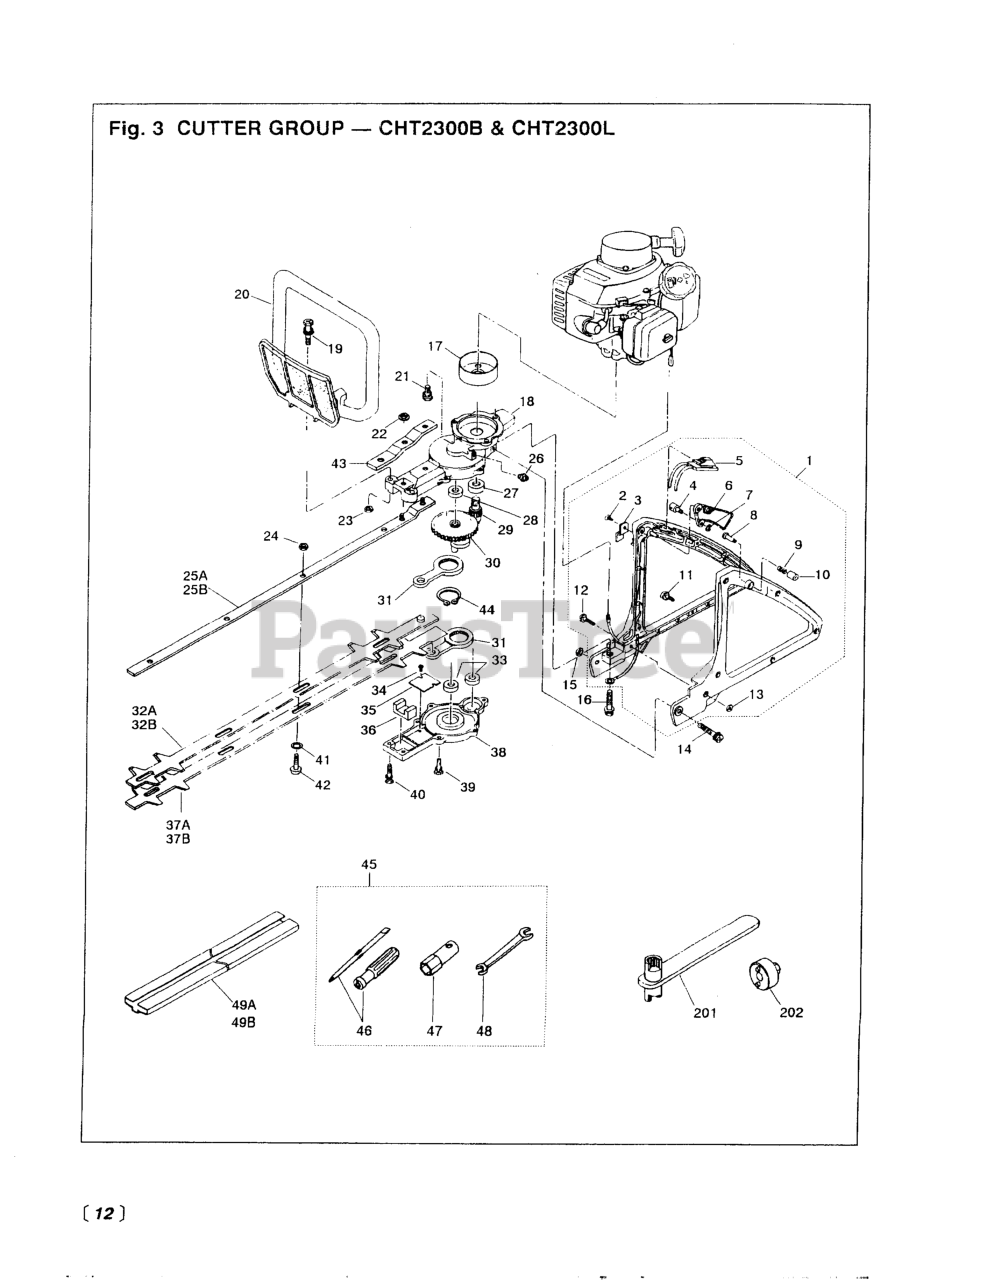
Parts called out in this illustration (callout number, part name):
2	SCREW, M4 x 10
3	PLATE
4	END, CABLE
5	SWITCH
7	RING, SNAP
9	SPRING
10	CAP, PIN
11	SCREW, M4 X 16
12	SCREW, M4 x 30
13	NUT, M6 X 4
14	BOLT, M6 X 50
15	NUT, M6 X 5
16	BOLT, M6 X 40
17	DRUM, CLUTCH
18	CASE, MIDDLE (RPLS -11110)
20	HANDLE (RPLS -12101)
21	BOLT, M6 X 14
22	NUT
23	NUT, M6 X 5
24	NUT, M6
26	FITTING, GREASE
27	BEARING
28	BEARING
29	PINION
30	GEAR COMPLETE
31	ROD
32A	BLADE, UPPER DOUBLE, 24
33	BEARING
34	SCREW, M3 x 5
35	PLATE
36	FELT
37A	BLADE, LOWER DOUBLE, 24
38	CASE, LOWER
39	BOLT, M5 x 16
40	BOLT, M5 X 20
43	PLATE (RPLS 3880-11130)
44	RING, SNAP, M25 X 1.2
45	TOOL SET
46	SCREWDRIVER
47	SOCKET, HEX, 3/4
48	SPANNER, 8 X 10 (RPLS 2540- )
49A	COVER, BLADE (24
202	WRENCH (TOOL)
